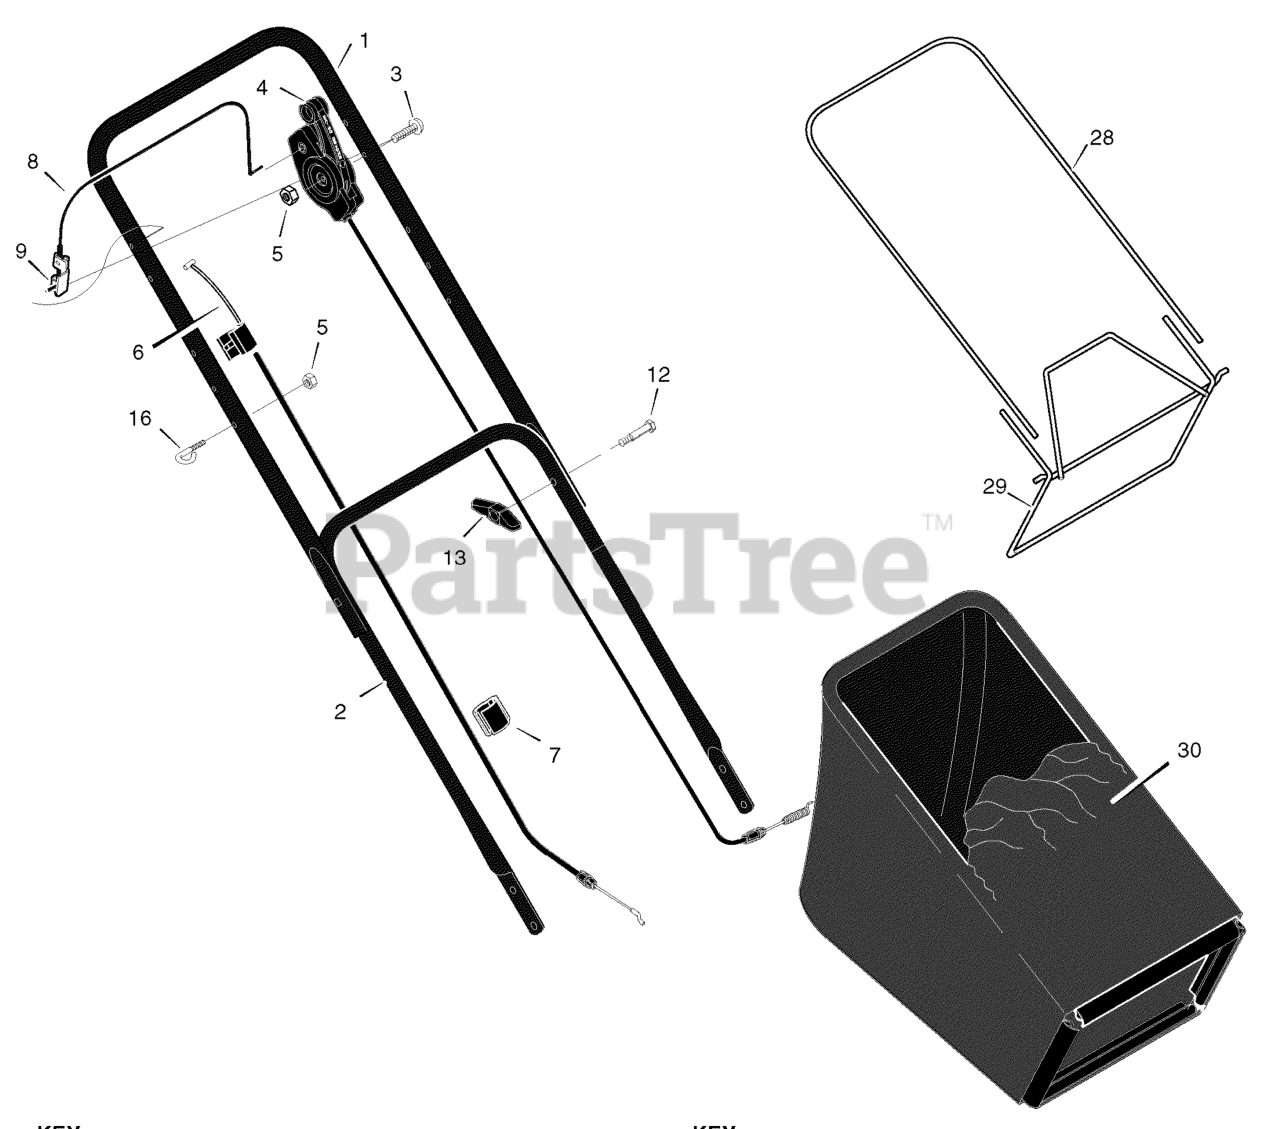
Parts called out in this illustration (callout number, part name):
1	Handle, Upper (Gray)
2	Handle, Lower (Gray)
4	Cable, Drive
5	Locknut
6	Cable, Stop
7	Fastener, Cable
8	Engine Stop Lever
9	Bracket, Stop Lever
16	Guide, Rope
28	Frame, Top
29	Frame Assembly
30	Bag, Cloth
